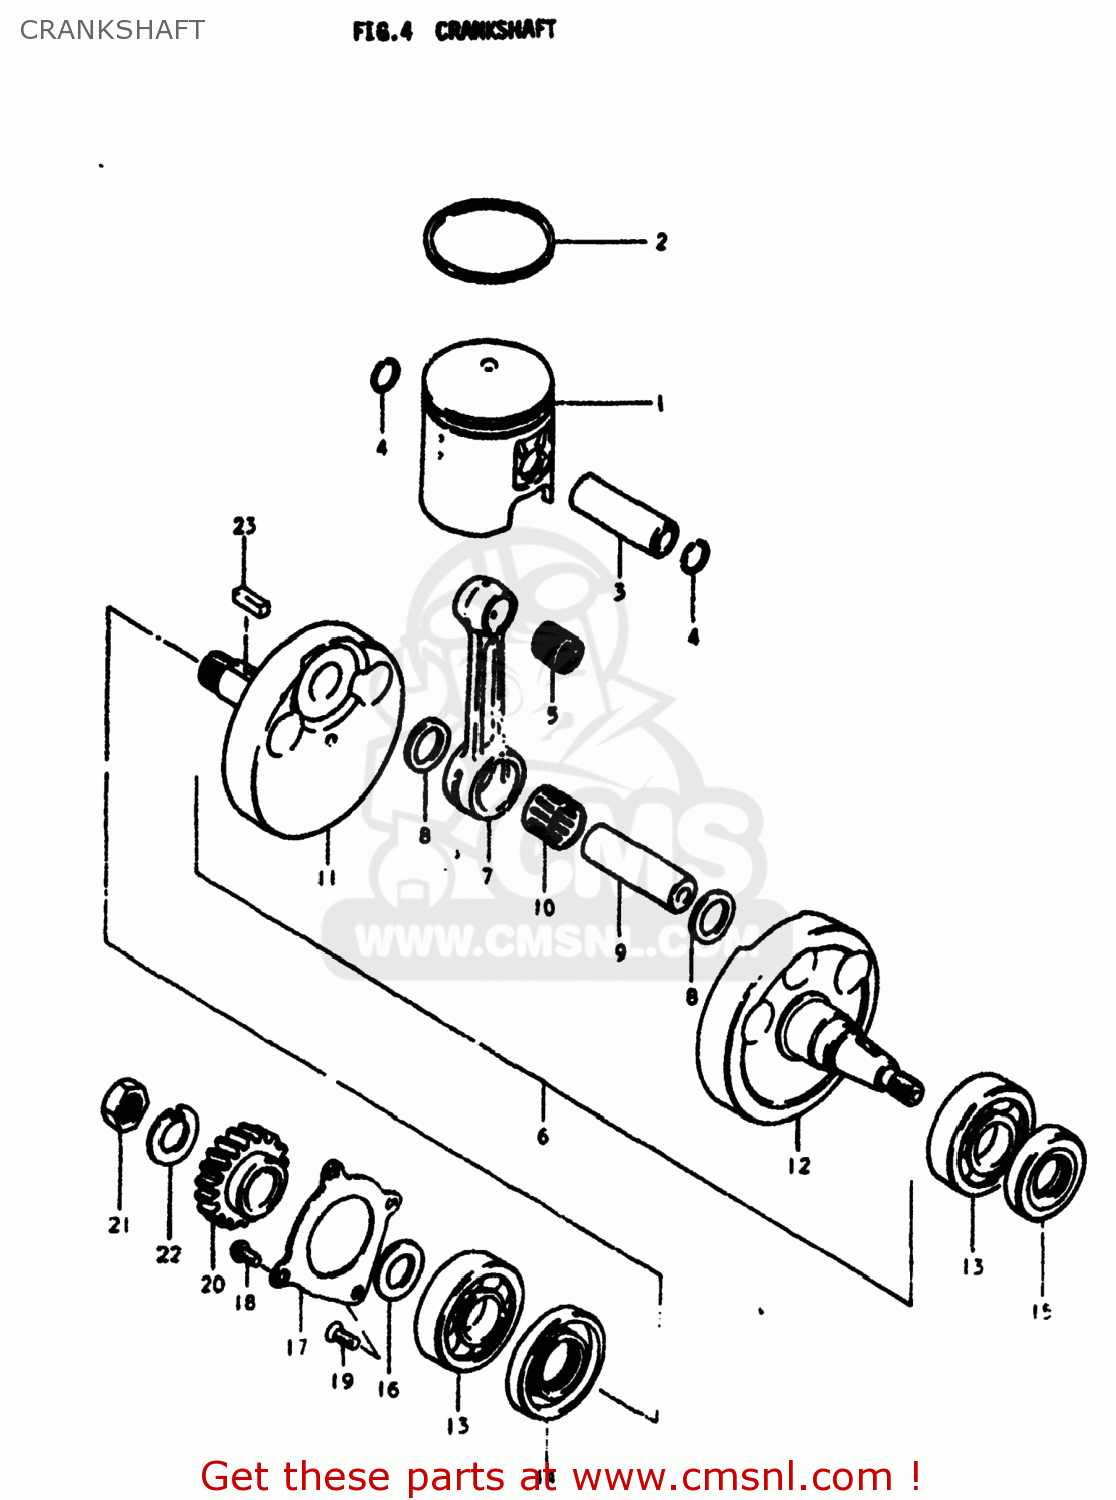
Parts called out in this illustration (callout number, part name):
1	PISTON
2	RING,PISTON
3	PIN,PISTON (18MM)
4	CIRCLIP
5	BEARING(18X23X22)
6	CRANKSHAFT ASSEMBLY
7	ROD,CONNECTING
8	WASHER(24X29X1.5)
9	PIN,CRANK
10	BEARING
11	CRANKSHAFT
12	CRANKSHAFT,LEFT
13	BEARING
14	SEAL,OIL(40X72X9)
15	SEAL,OIL(24X50X9)
16	WASHER
17	PLATE
18	SCREW 6X12
19	SCREW
20	GEAR,PRIMARY DRIVE
21	NUT (20MM)
22	WASHER
23	KEY
